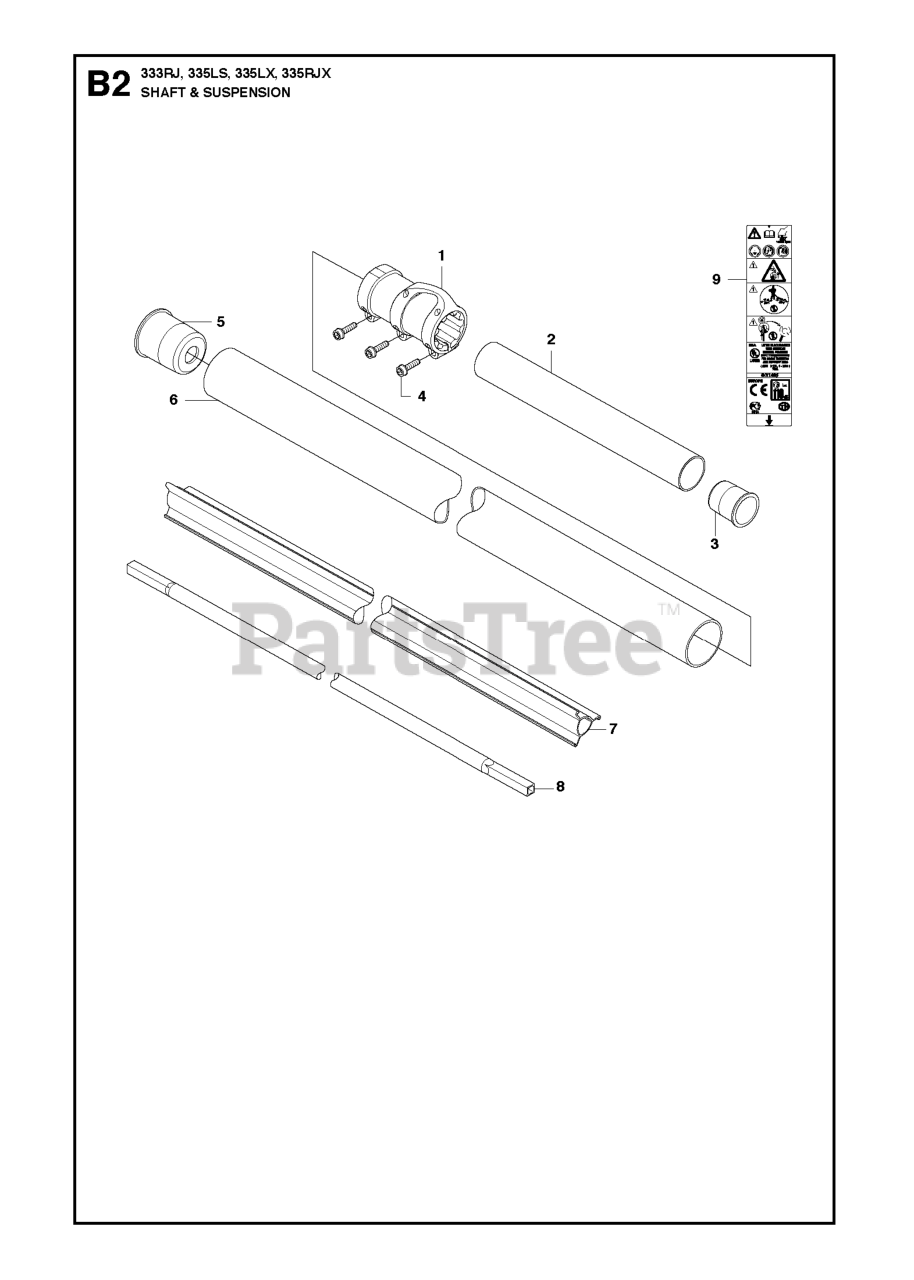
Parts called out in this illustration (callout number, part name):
1	SLEEVE
2	TUBE
3	SPACER SLEEVE
6	TUBE
7	GUIDE
8	SHAFT
9	RP WARNING DECAL
